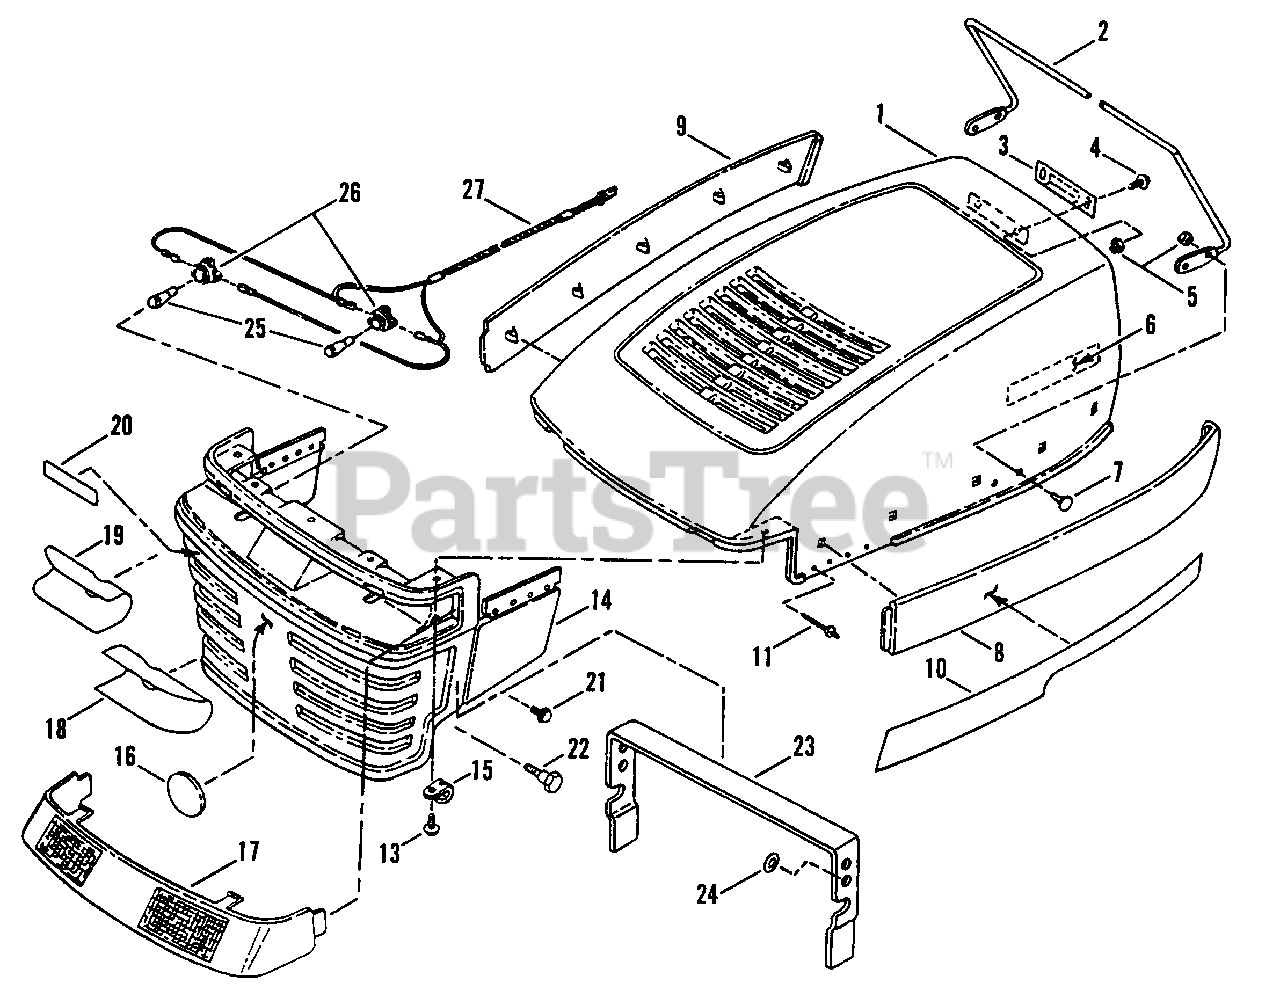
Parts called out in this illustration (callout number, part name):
1	HOOD
1	HOOD, Mozart
2	ROD, Hood Support
3	LATCH, Spring
4	SCREW, 1/4-20 x 5/8" Truss Head, Torx
5	NUT, 1/4-20 Hex Nyloc
6	DECAL - SNAPPER, 8" Molded Logo, White Letters
6	DECAL - SNAPPER, 8" Molded Logo, Silver Letters
7	BOLT, 1/4-20 x 5/8" Flat Head Carriage
8	PANEL, Hood (Left Hand)(Black)
9	PANEL, Hood (Right Hand)(Black)
10	DECAL, Hood (Right Hand)
10	DECAL, Hood (Left Hand)
10	DECAL, Hood (Right Side)
10	DECAL, Hood (Left Side Shown)
11	RIVET, 1/8" Pop
13	SCREW, M4.8 x 1.59 x 16.00MM, Special
14	GRILL, Hood
15	CLIP, "J"
16	DECAL, Molded Medallion
17	LENS, Grille (Headlights)
18	DECAL, Reflect (Left Hand)
19	DECAL, Reflect (Right Hand)
20	DECAL - SNAPPER, 4" Molded Logo
21	SCREW, 5/16-18 x 1/2" Self - Tapping
22	BOLT, Shoulder, 3/8-16 x 1-1/4" Hex Socket, Torx
23	BRACE, Hood Support
24	RETAINER, Bolt
25	BULB, Headlights
26	SOCKET, Headlight Bulb
27	HARNESS, Headlight Wiring
